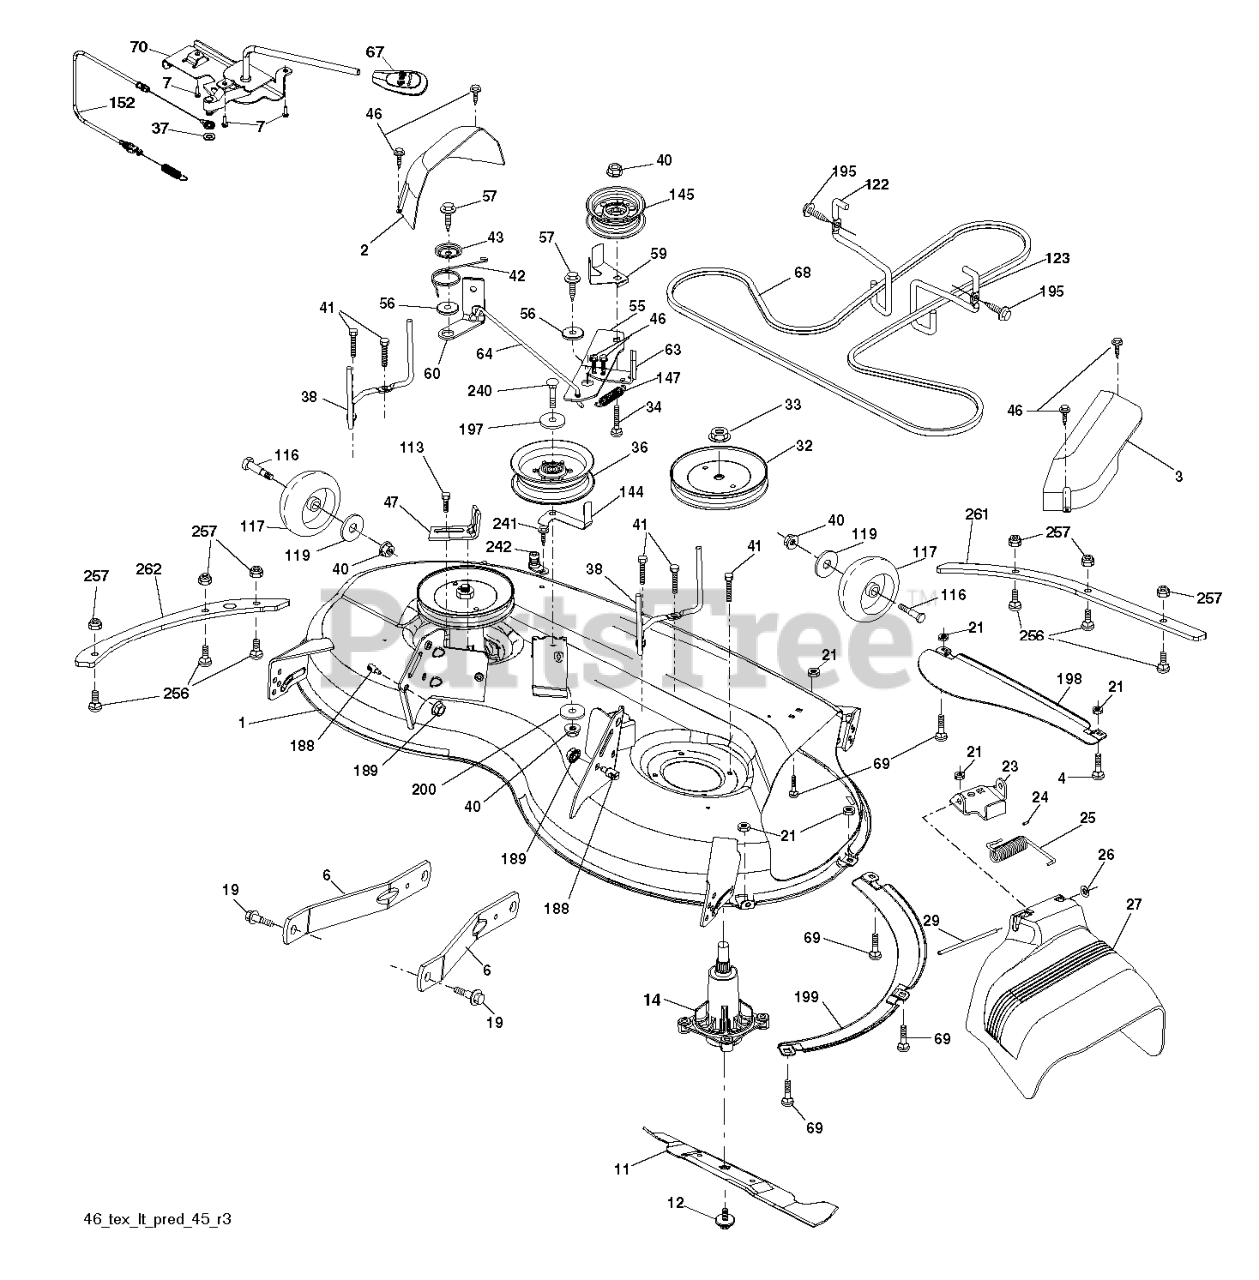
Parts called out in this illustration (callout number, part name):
1	KIT SVC DECK WELDMENT
2	COVER.MANDREL.RH.46"
3	COVER.MANDREL.LH.46"
4	SCREW HEXAGON HEAD SCREW 5/16-
6	ARM.SUSPENSION.MOWER.R
11	BLADE.MOWER.46".HI.LIFT
12	SCREW.SEMS.7/16-20X1.HEX.HEAD
14	KIT.MANDREL.NONGREASE.TALL
19	BOLT.SHOULDER
23	BRKT.DEFLECTOR.38"2005+
24	CAP-SLEEVE LT
25	SPRING.TORSION.DEFLECT
26	NUT PUSH M
27	SHIELD.DEFLECTOR.MOWER.46"BLAC
32	PULLEY.MANDREL.5.438.PD
34	GSPW Bolts
36	PULLEY.IDLER.2006
37	WASHER PLAIN WASHER 3/8 X 0.08
38	KEEPER.BLT.PNT.MNDRL.PULL.6.25
40	NUT LOCK FLG 3/8-16 UNC
41	BOLT.HEX.WASHR.HED.313-18X1.19
42	SPRING.TORSION.BRAKE
43	SRPING.TORSION.RETAINE
46	SCREW.1/4-20X5/8
47	BRKT.CLUTCH.CABLE
56	SPACER.RETAINER
57	SCREW 3/8-16X1
59	GUARD, BELT
60	ARM BRAKE MOWER RH 38"
63	ARM BRAKE MOWER
64	LINKAGE BRAKE
67	HANDLE.CLUTCH.CABLE.LT
68	V-BELT
70	CLUTCH.ASM.MANUAL.YT.PREDATORQ
113	BOLT.5/16HEX.WHS.HD
117	WHEEL.GAUGE.RALLY
122	KEEPER BELT ENGINE LH
123	KEEPER BELT RH
144	KEEPER.BELT.MOWER
145	PULLEY.IDLER.48"PRIMARY
147	SPRING RETURN
152	CABLE.MECHANICAL.CLUTCH
188	STUD.W/"D"ANTI-ROTATION
195	SCREW, 3/8-16X3/4
198	BAFFLE CENTER FRONT
199	BAFFLE FRONT RH
200	WASHER.13/32 X 1 X 1/2.11GUARD
240	BOLT-HEX EAK
241	SCREW.TT.#10-32X.5.3/8.FLANGE
242	PORT.WASHOUT
256	BOLT CUP HEAD SQUARE NECK BOLT
257	NUT T
261	PLATE.REINF.DECK.46".FRONT.BLK
262	PLATE.REINF.DECK.46".SIDE.BLK
